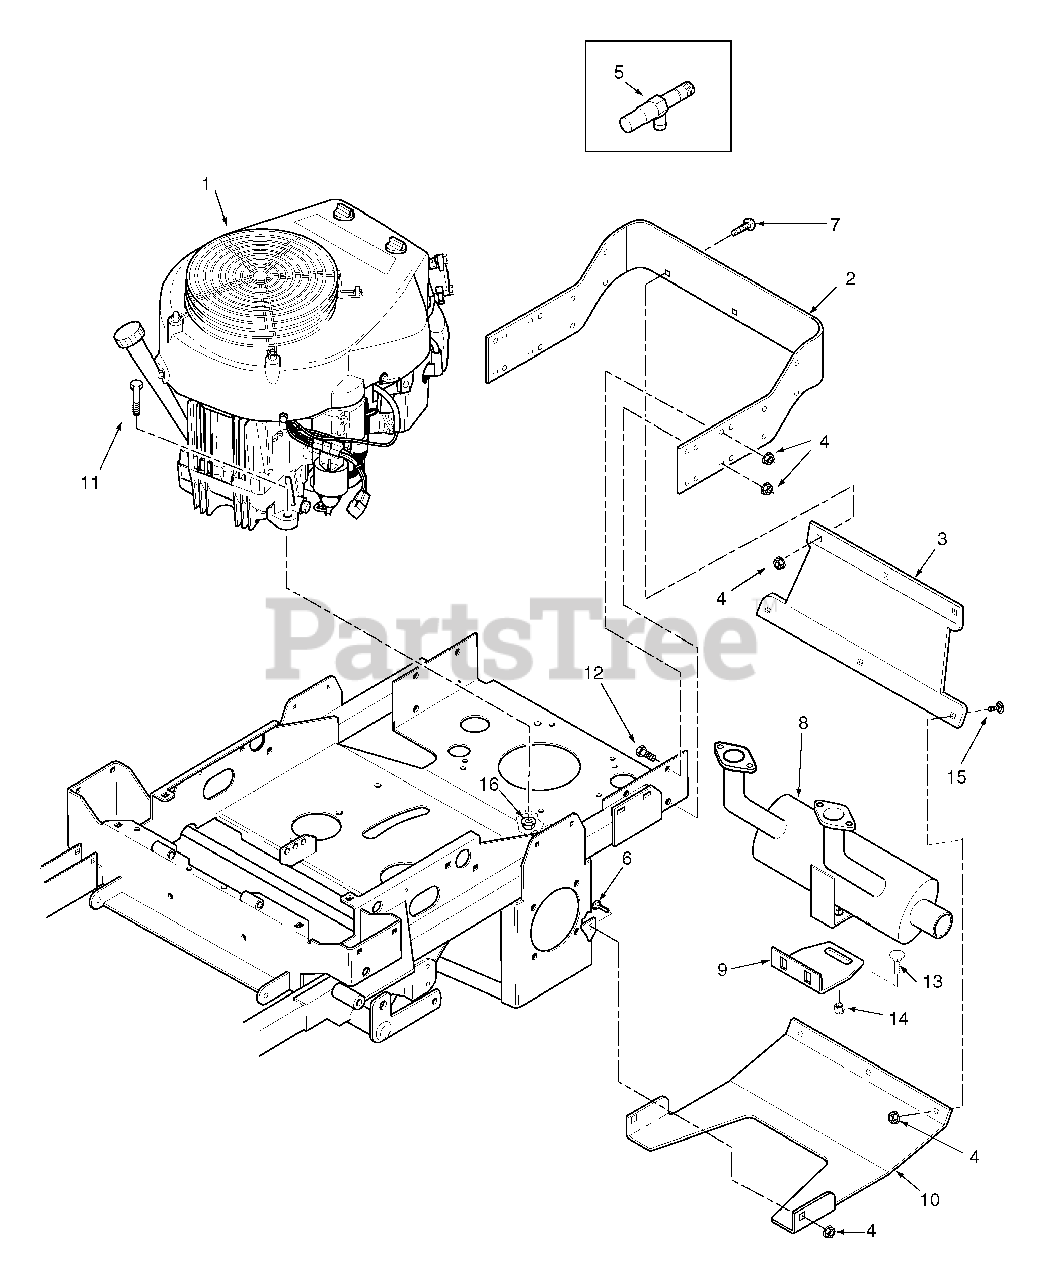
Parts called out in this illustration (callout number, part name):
1	Engine, Kawasaki (FH641V-AS27)
2	Bumper, Rear
3	Shield, Rear
4	Nut, Serr. Flange 3/8-16
5	Extension, Oil Drain 4"
6	Bolt, Carr. 3/8-16 x 1"
7	Bolt, 3/8-16 x 1" Torx
8	Muffler
9	Bracket, Muffler
10	Plate, Skid
11	Bolt, Hex Head 5/16-18 x 1-1/2"
12	Bolt, Hex Head 3/8-16 x 1"
13	Bolt, Hex Head 5/16-18 x 3/4"
14	Nut, Serr. Flange 5/16-18
15	Bolt, Carr. 3/8-16 x 3/4"
16	Nut, Serr. Flange 5/16-18
